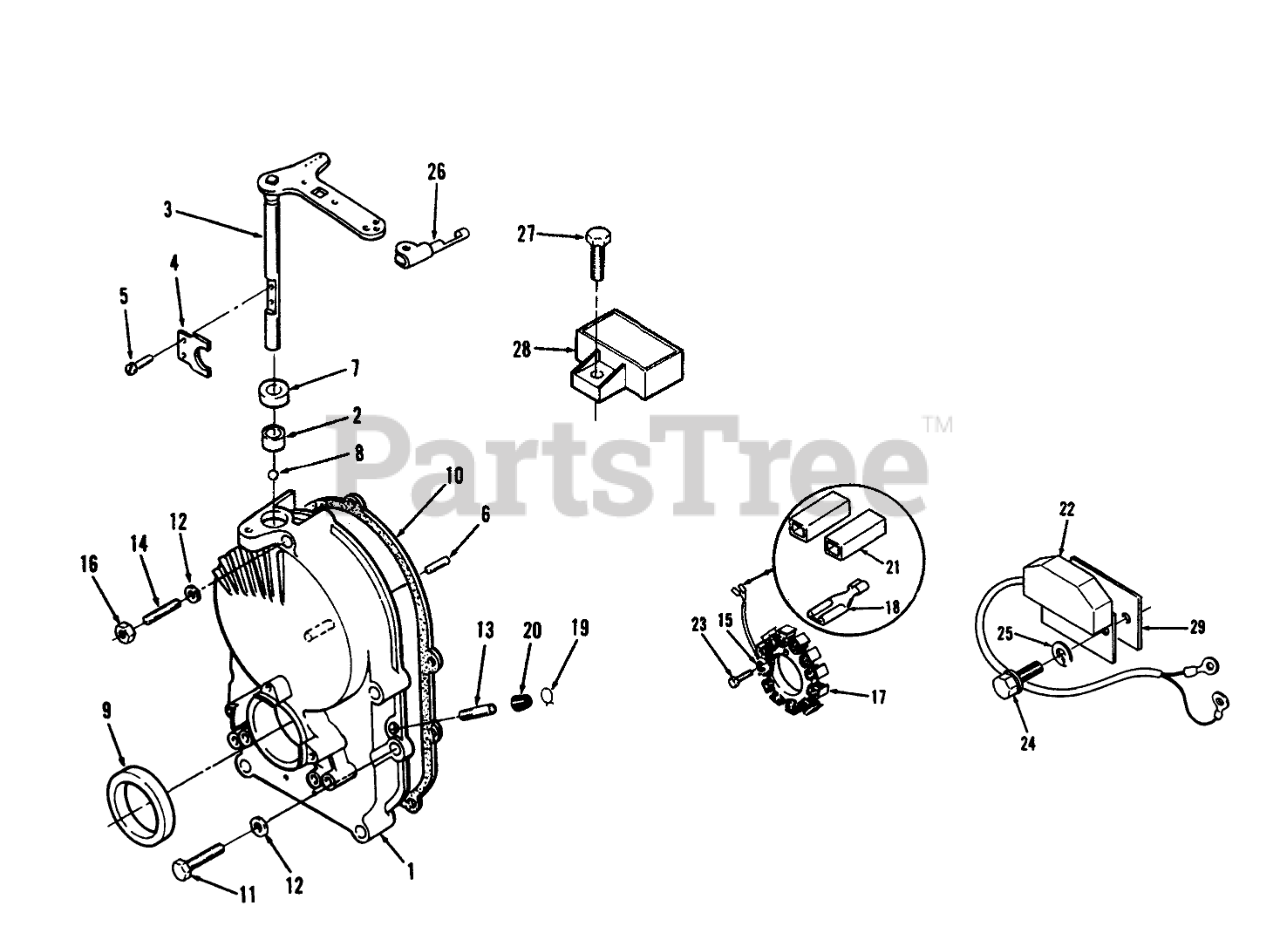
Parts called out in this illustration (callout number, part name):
1	GEAR-CASE KIT
2	Bearing
3	SHAFT AND ARM
4	YOKE
5	Screw
6	Washer
7	SEAL
8	BALL
9	SEAL
10	Gasket
11	Bolt
12	WASHER
13	Vacuum Tube
14	Stud
15	Washer-Lock
16	Nut
17	Stator (Includes Terminals)
18	Stator Leads Terminal
19	CLAMP
20	CAP-FUEL OUTLET
21	Body-Terminal Connector Kit (Includes Terminals)
22	Control-Ignition
23	Screw-HH
24	Bolt
25	WASHER-LOCK
27	SCREW-HWH
28	Regulator
29	Insulator
